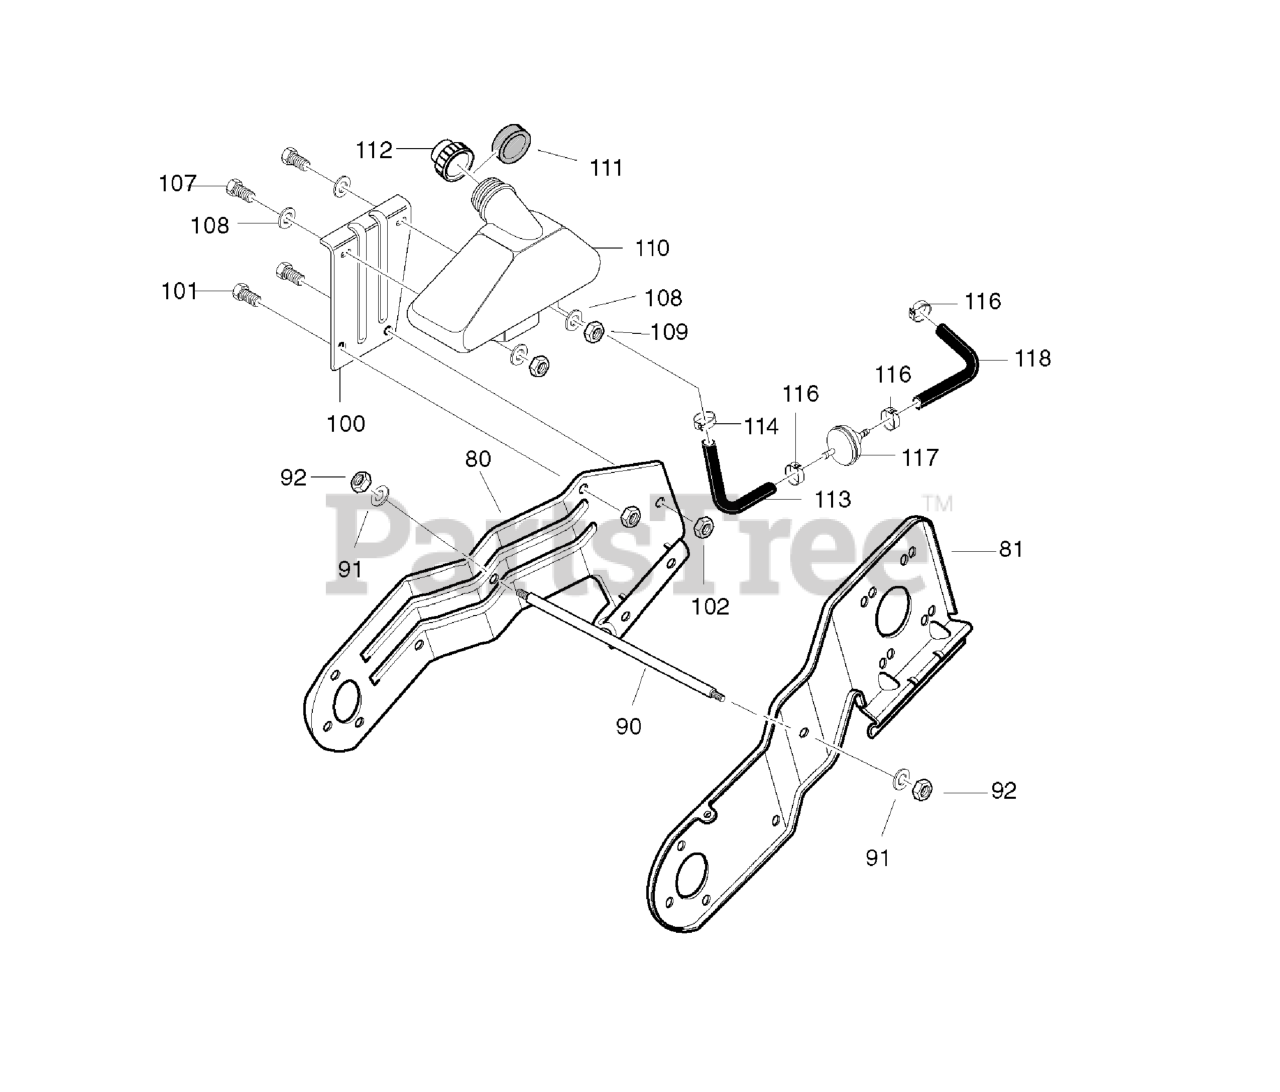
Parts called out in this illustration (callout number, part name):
80	FRAME, SIDE SUPT STEEL RH
81	FRAME, SIDE SUPT STEEL LH
90	ROD, SUPPORT
91	WASHER
92	NUT, 3/8-16 HEX
100	BRACKET, GAS TANK
101	SCREW, 1/4-20 X .75
102	NUT, 1/4-20 HEX
107	SCREW, 1/4-20 X .75
108	WASHER, FLAT
109	NUT, 1/420 HEX
110	TANK, FUEL
111	RING, FOAM FUEL TANK
112	CAP, GAS
113	TUBING 8 INCH
114	CLAMP, HOSE SCREW
116	CLAMP, HOSE
117	FILTER IN LINE
118	TUBING, 6 INCH
